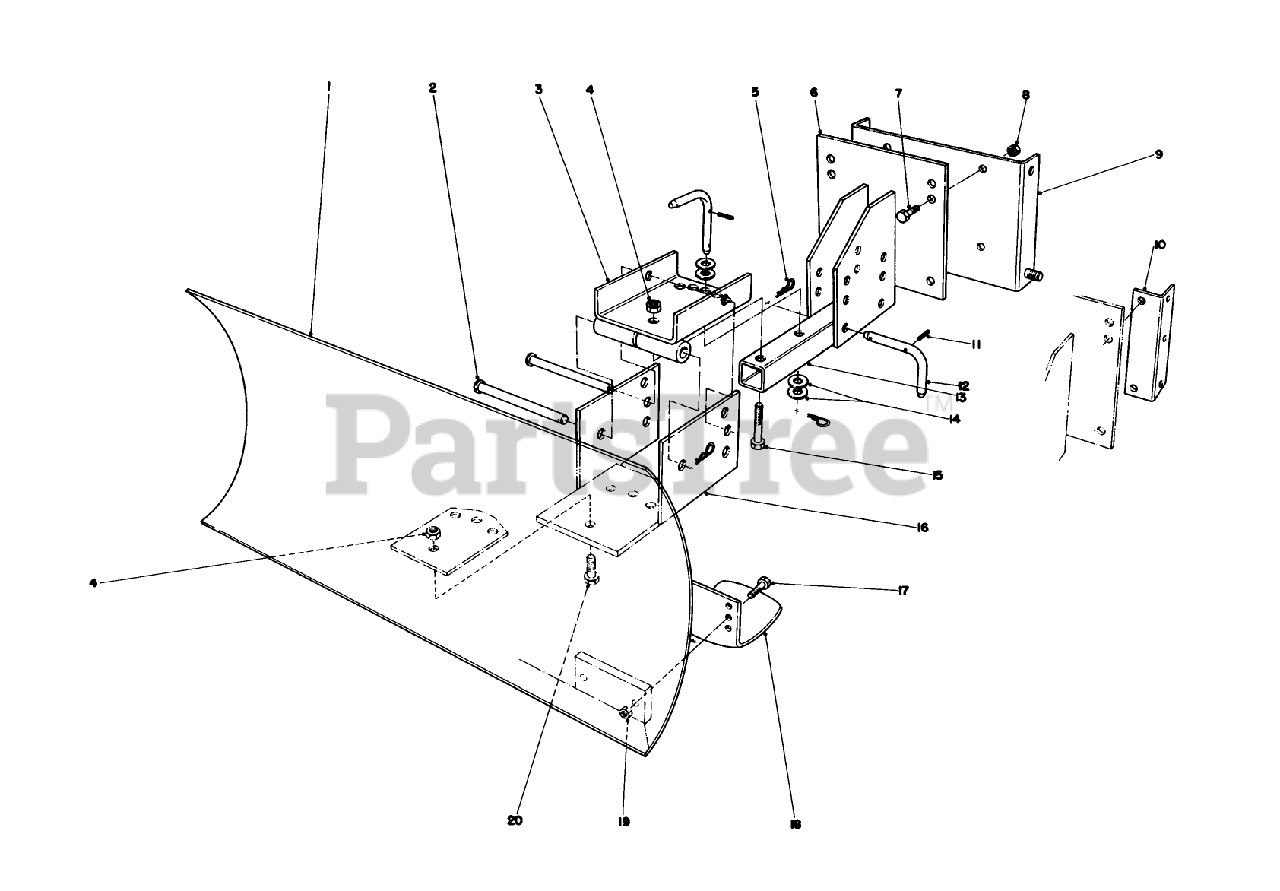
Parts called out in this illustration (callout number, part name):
2	PIN-CLEVIS
5	PIN-HAIR
7	SCREW-HH
8	NUT-LOCK, CONE
11	PIN-SPRING
14	WASHER-FLAT
15	SCREW-HH
17	SCREW-HH
19	NUT-LOCK, CONE
20	SCREW-HH
